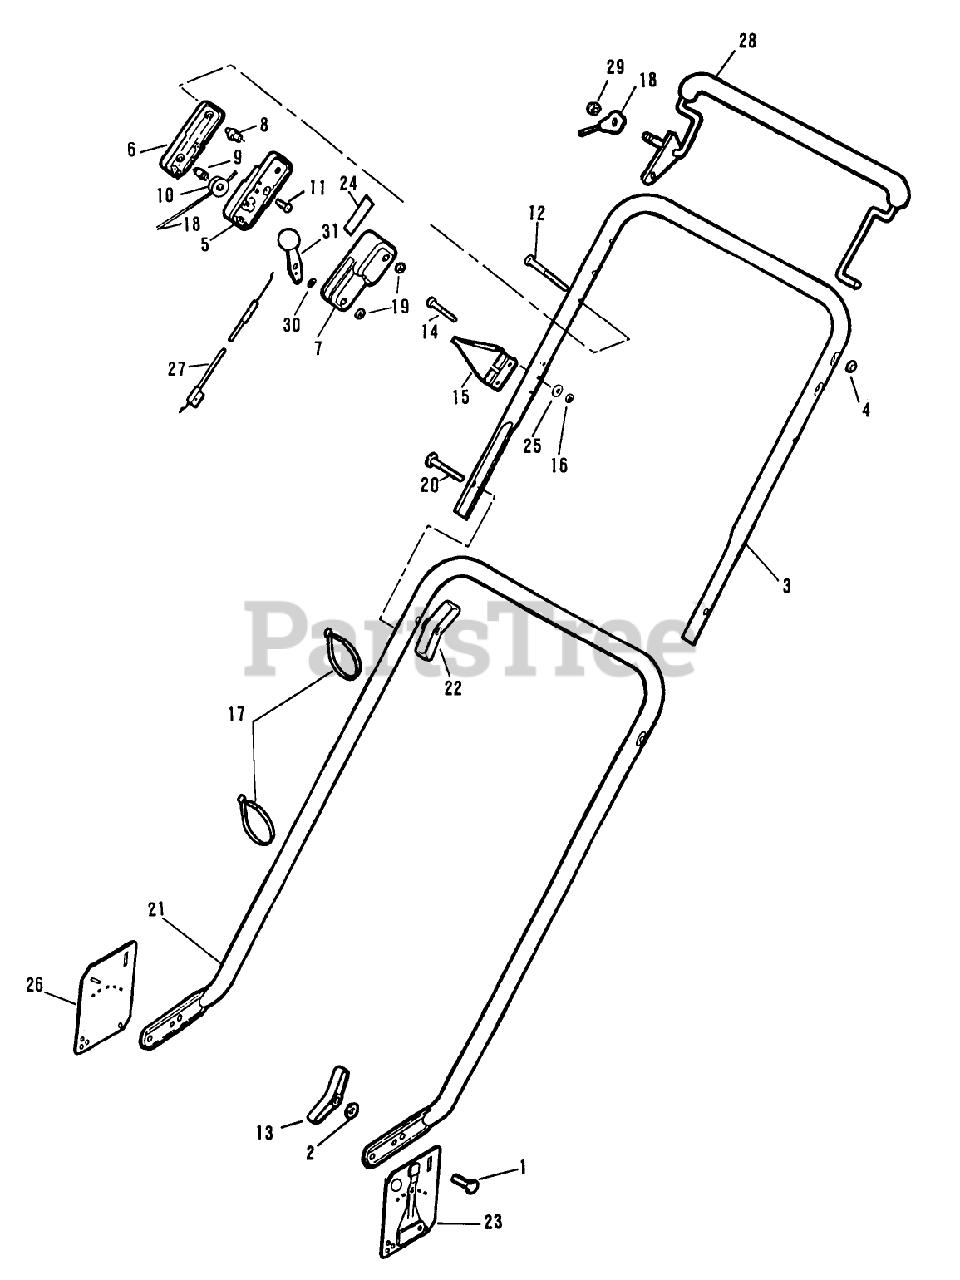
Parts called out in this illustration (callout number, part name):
6	OUTER CONTROL CASE
9	PIN SKF
10	PULLEY PL
13	NUT WING
16	LOCKNUT E
18	CONTROL CABLE
19	NUT C/LOCK E
20	BOLT QUALITY
22	NUT-WING
27	CABLE TH'TTLE WES
28	CONTROL LEVER ARG
29	NUT ACORN
30	WASHER-SPRING
31	LEVER&KNOB AY WES
